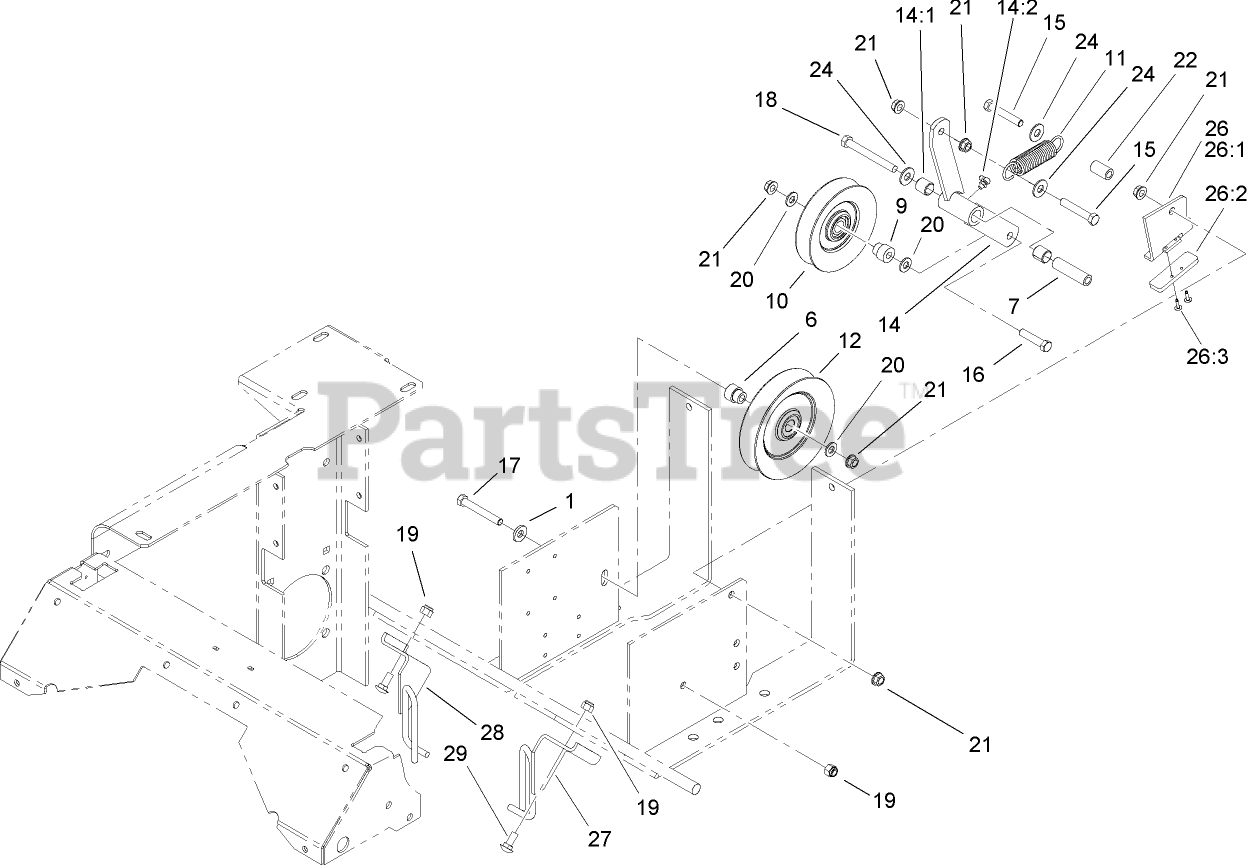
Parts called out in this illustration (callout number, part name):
1	WASHER-BELLEVILLE
6	Bushing-Idler
7	BUSHING-PIVOT, IDLER
9	BUSHING-IDLER
10	Idler
11	SPRING-EXTENSION
12	PULLEY-IDLER
14	Arm ASM
14:1	SLEEVE-BEARING
14:2	FITTING-GREASE, 90 DEG
15	SCREW-HH
16	SCREW-HH
17	SCREW-HH
18	SCREW-HH
19	NUT-LOCK, NI
20	WASHER-FLAT
21	NUT-HHF, WHIZ
22	SPACER
24	WASHER-FLAT
26	Travel Limiter ASM
26:1	Plate-Limiter, Pulley
26:2	PAD-BUMPER
26:3	RIVET
27	GUIDE-BELT, LH
28	GUIDE-BELT, RH
29	BOLT-CARR
